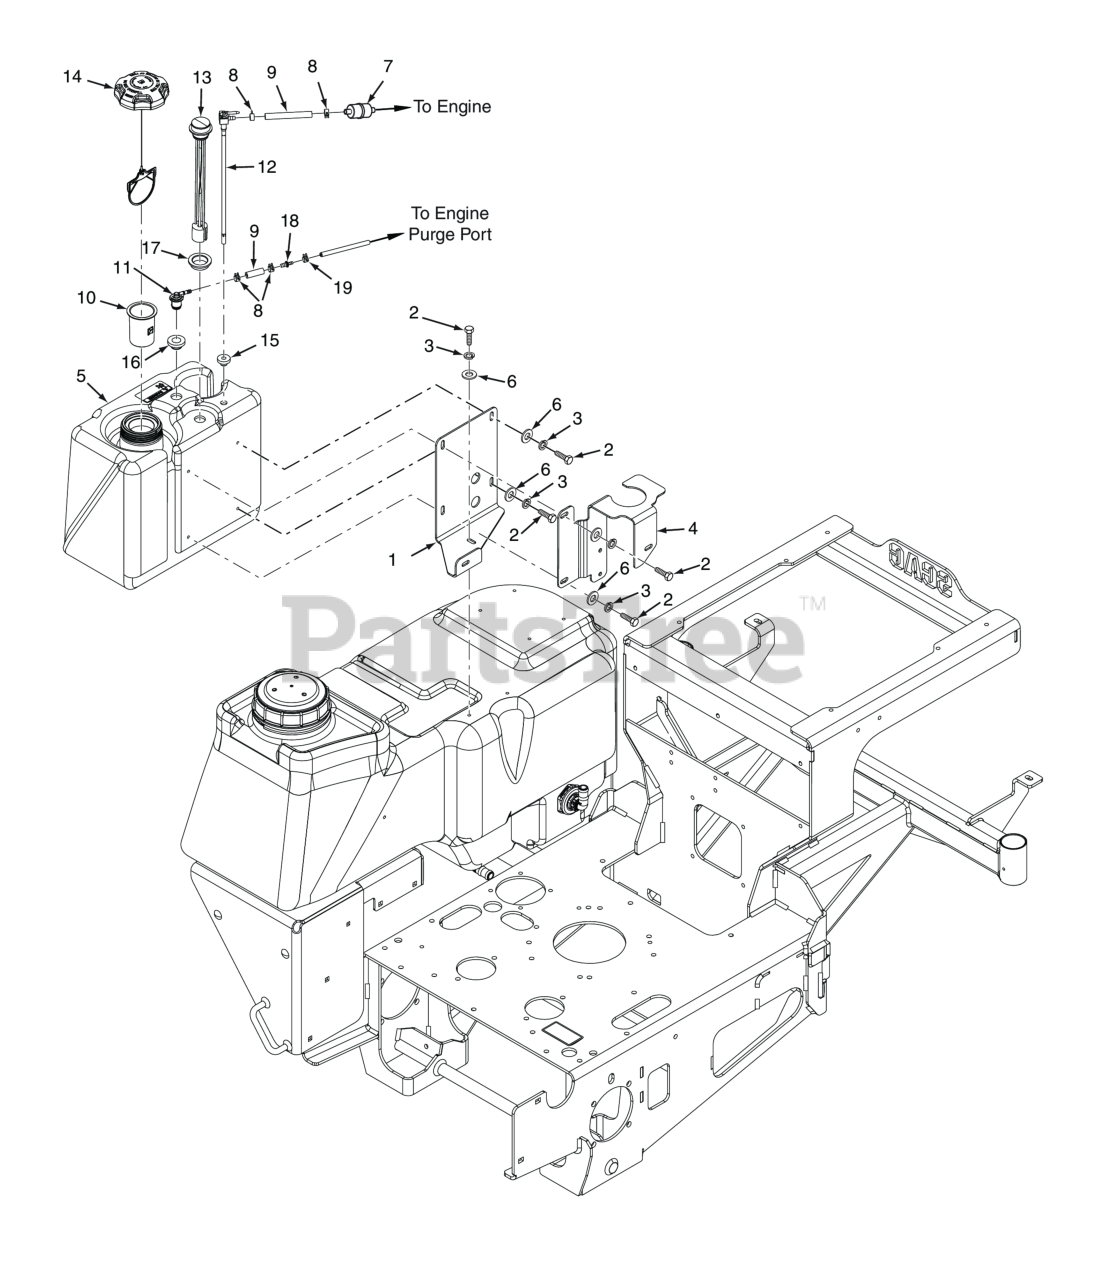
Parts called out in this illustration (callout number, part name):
1	Mounting Bracket, Fuel Tank
2	Bolt, Hex 5/16 - 18 x .75 - Stainless Steel
3	Lockwasher, 5/16 (.317 x .586 x .078) Helical Spring
4	Mounting Bracket, Oil Reservoir
5	Fuel Tank Assembly (incl. #2, 3, 5, 6, 17, 18)
6	Washer, Flat 5/16 -.375 x .875 x .0547/.104 - Stainless Steel
7	Fuel Filter
8	Clamp, Fuel Hose 1/4" Hose I.D.
9	Hose, 1/4" Vapor Recovery (order by inch)
10	TUBE, FUEL INLET - 3.00
11	Remote Vent, No Valve
12	Valve, Fuel Shutoff w/Screen
13	Fuel Gauge Assembly
14	Fuel Cap w/ Tether (E.P.A.)
15	Bushing, 0.56" Dia. Viton
16	Grommet, Viton,
17	Grommet, Fuel Gauge
18	Mender, 1/4 x 3/16 w/0.02 Hole
19	Clamp, Vapor Recovery Hose 3/16"
